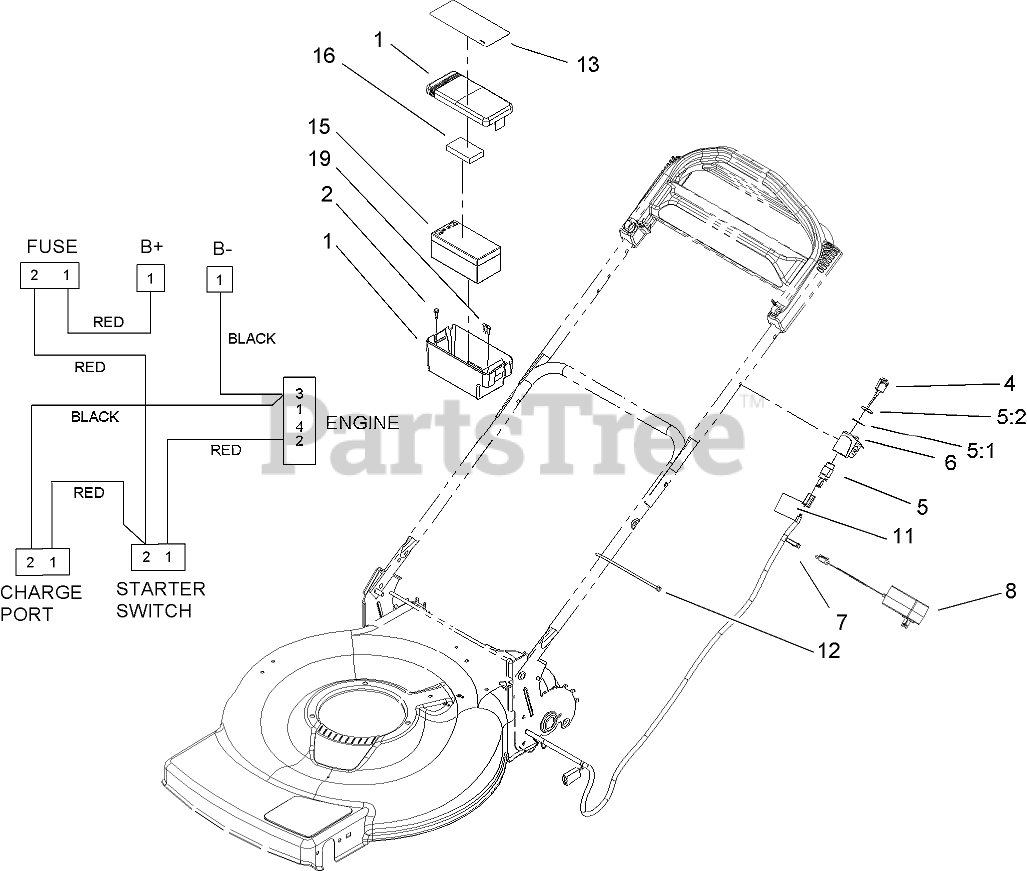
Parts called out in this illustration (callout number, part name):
1	BATTERY BOX ASM
2	SCREW-FORMING, THREAD
5	STARTER SWITCH ASM
5:1	WASHER-TOOTH, INTERNAL
5:2	NUT-HH
6	MOUNT-SWITCH
7	HARNESS-WIRE
8	CHARGER-12 VOLT
11	DECAL-WARNING
12	TIE-CABLE
13	DECAL-INSTRUCTIONAL
15	BATTERY-WET
16	FOAM-BATTERY, TOP
19	FUSE-40 AMP
